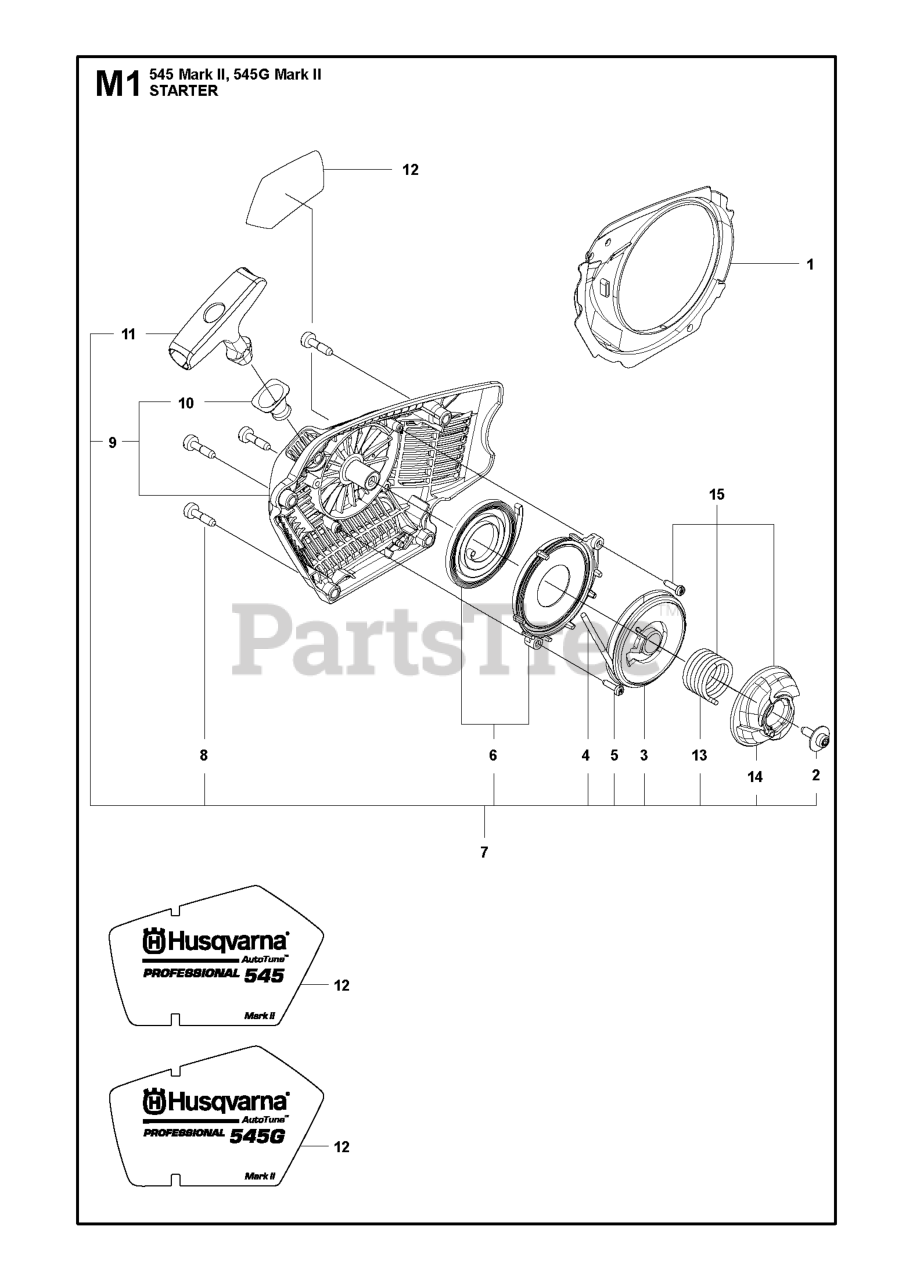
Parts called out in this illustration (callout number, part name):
1	COOLING AIR CONDUCTOR
2	SCREW ITXSCT MT5X16 10.9 TBO
4	STARTER ROPE
5	SCREW CITXPANT
6	SPRING CASSETTE ADDY
7	STARTER ASSY KIT SPARE PART H5
8	SCREW CITXPANMO
9	STARTER HOUSING
12	LABEL
13	TORSION SPRING
14	DRIVER ASSY
15	STARTERS
